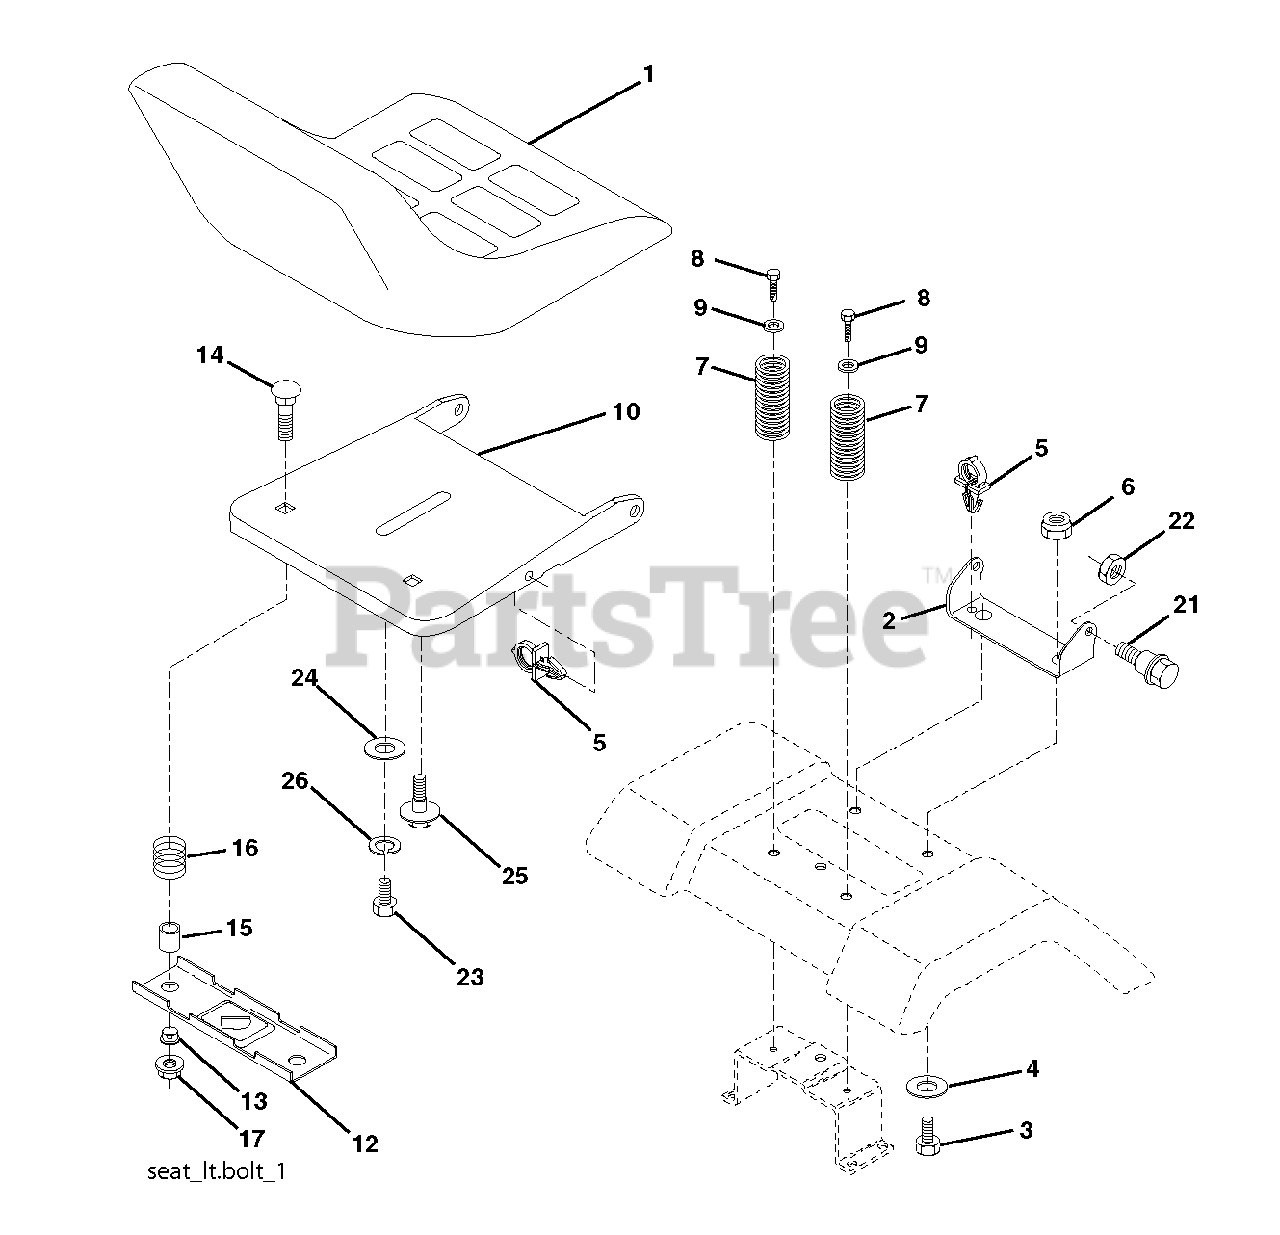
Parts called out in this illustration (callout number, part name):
1	SEAT.XG090.BLK.KB/BLT.NO-LOG
2	SEAT PIVOT BRKT
4	WASHER PM
5	PUSH CLIP
6	NUT
7	SPRING COMPRESSION
8	SCREW 3/8-16X1
9	WASHER
10	PAN.ASM.SEAT.1SLOT
12	BRKT.MNTNG.SWITCH.SEAT
14	BOLT.ROUND.HEAD.SQUARE.NECK
15	SPACER SPLIT 28X.96
17	NUT T
21	BOLT.SHOULDER.5/16-18
22	NUT.71038.31-18.HEX.NYLOCK
23	BOLT.HEX.BLACK
25	BOLT,SHOULD
26	LOCKWASHER
